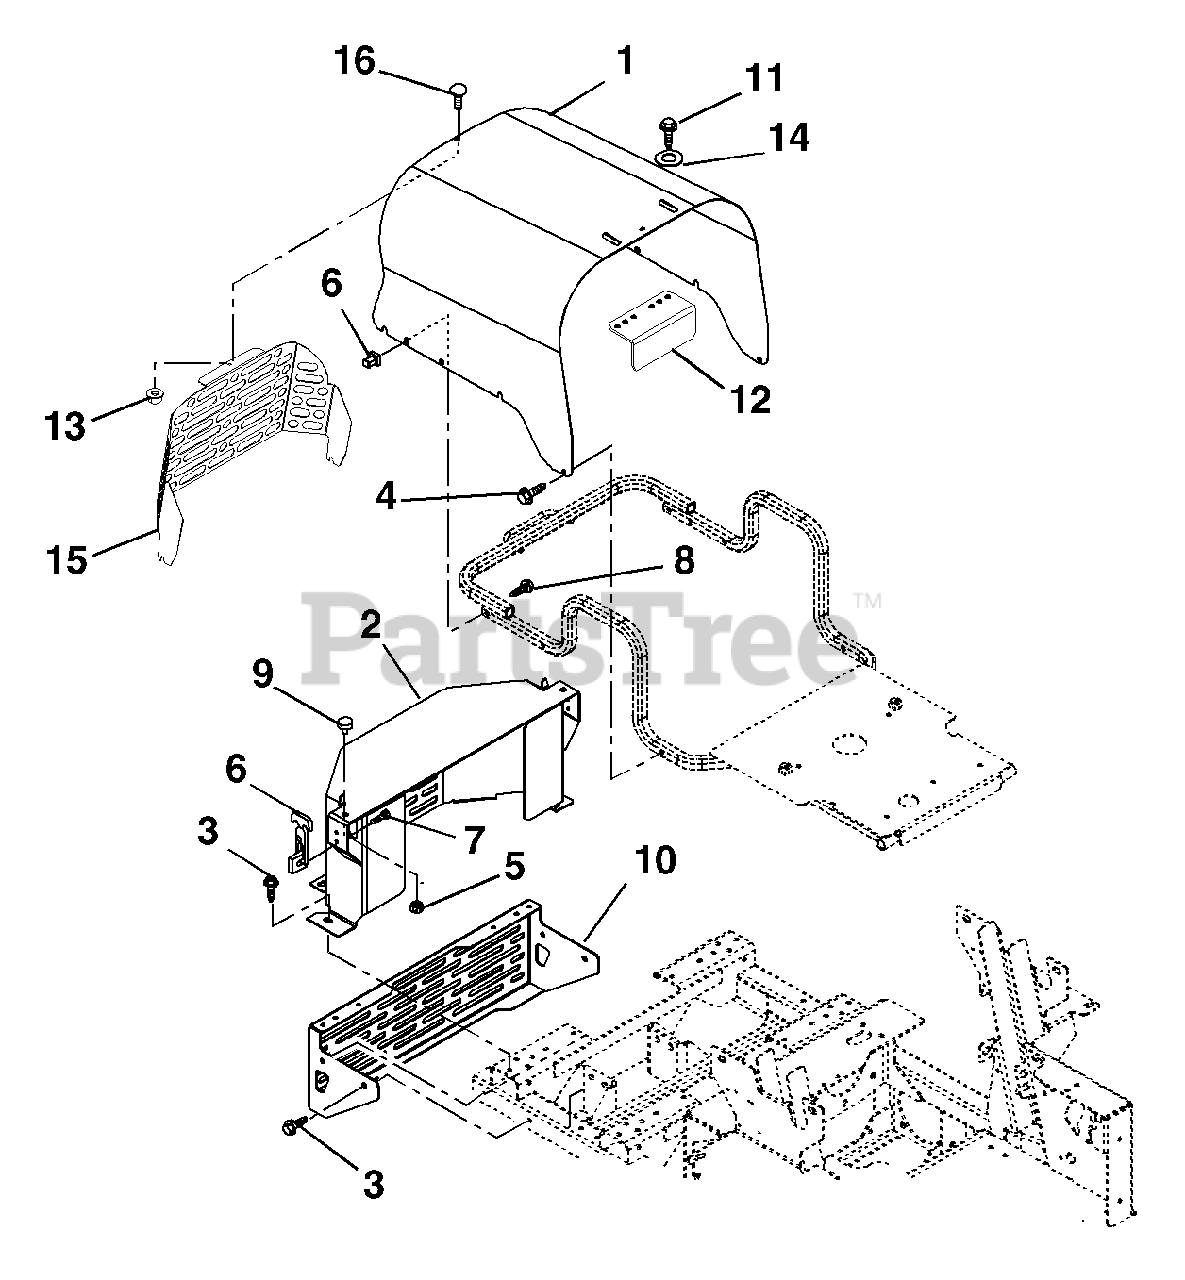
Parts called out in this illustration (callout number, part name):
1	L/C HOOD - RED
2	WMT, BELT GUARD (DIESEL)
3	@SCR-TAP .38-16X.75 HWH TR YWZ
4	@SCR-TAP .38-16X.50 HWH TR YWZ
5	@NUT-SPNLK-FLG .312-18 YWZC
6	LATCH, RUBBER
7	@SCR-MCH 10-24X.50 HWH YWZC
8	@SCR-MCH 10-24X1.50 HWH YWZC
9	BUMPER, RUBBER
10	WMT, BUMPER
11	@SCR-TAP .25-20X.50 HWH TR YWZ
12	COVER, RAD
13	@NUT-LK-TOP-FLG .25-20 YWZC
14	@WSHR-FL-STL.281X.62X.065 YWZC
15	L/C HOOD GUARD - BLACK
16	@BLT-RDHDSQNK .25-20X.50 G5YZ
